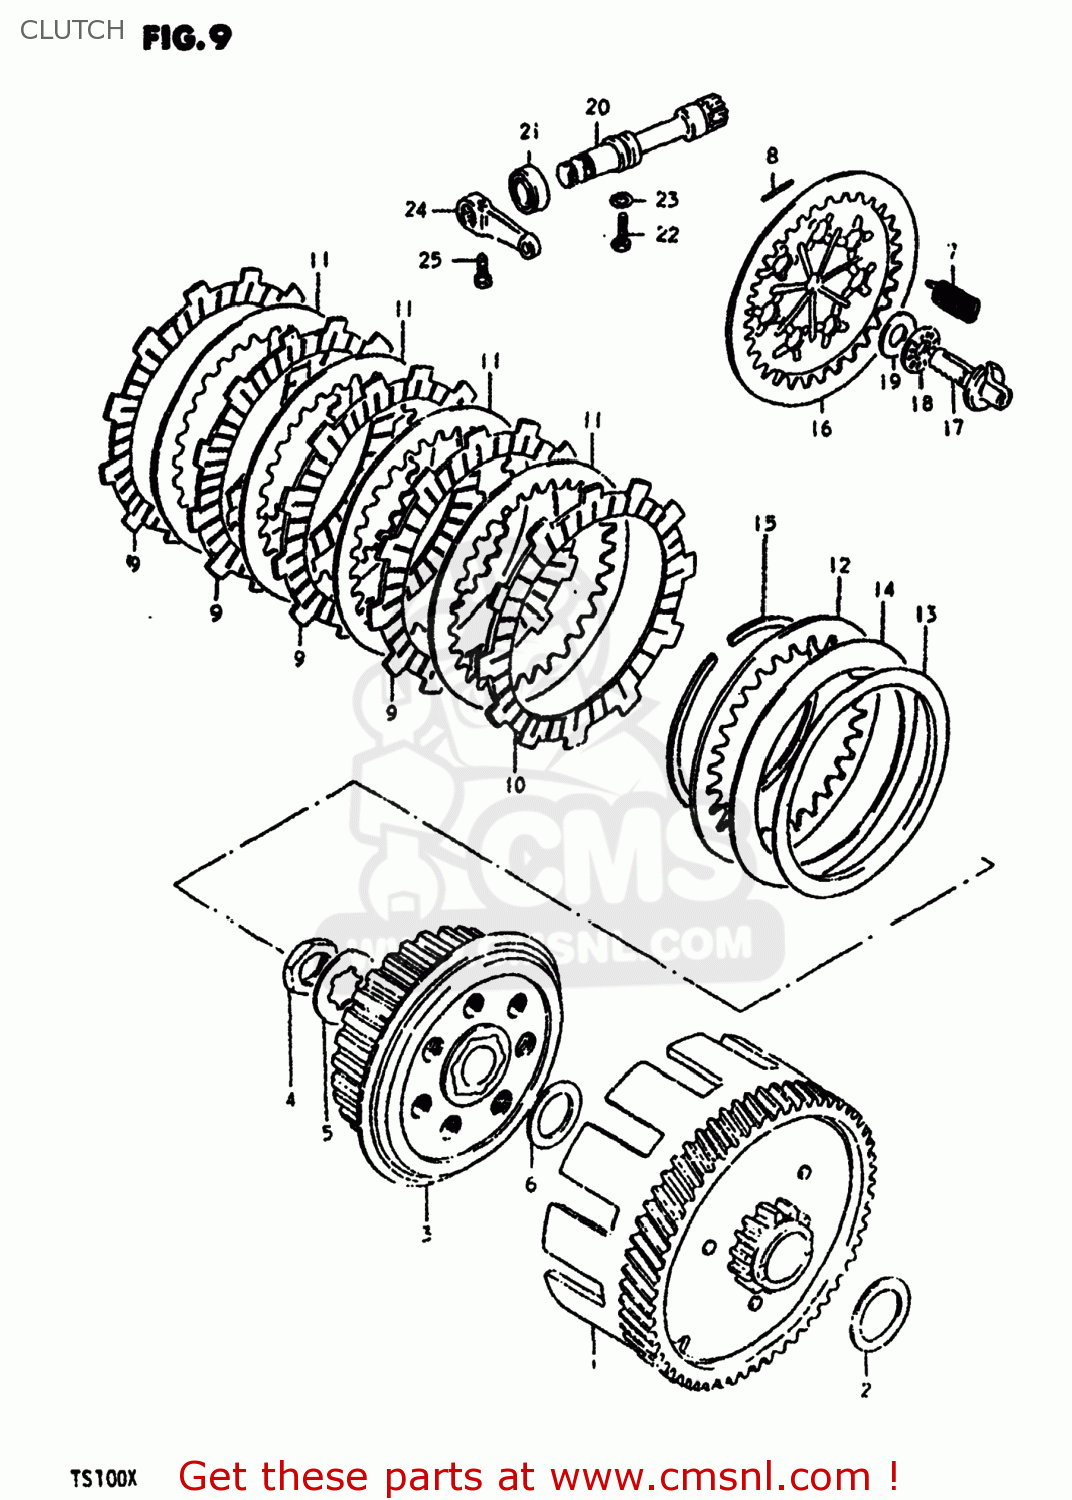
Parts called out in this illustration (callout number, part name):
1	GEAR ASSEMBLY,PRIMARY DRIVE
2	WASHER
3	HUB,CLUTCH SLEEVE
4	NUT
5	WASHER,LOCK
6	WASHER
7	SPRING
8	PIN(2.5X19.8)
9	PLATE,CLUTCH DRIVE
10	PLATE,CLUTCH DRIVE (MCA)
11	PLATE,CLUTCH DRIVEN (NAS)
12	PLATE,CLUTCH DRIVEN(T:2.0) (NAS)
13	SEAT,WAVE WASHER
14	WASHER
15	CIRCLIP
16	PLATE,CLUTCH PRESSURE
17	BACK,CLUTCH RELEASE
18	BEARING(10X22X2.8)
19	WASHER(10.1X21.4X0.8)
20	PINION,CLUTCH RELEASE
21	OIL SEAL
22	BOLT(6X12)
23	WASHER
24	ARM,CLUTCH RELEASE
25	BOLT
